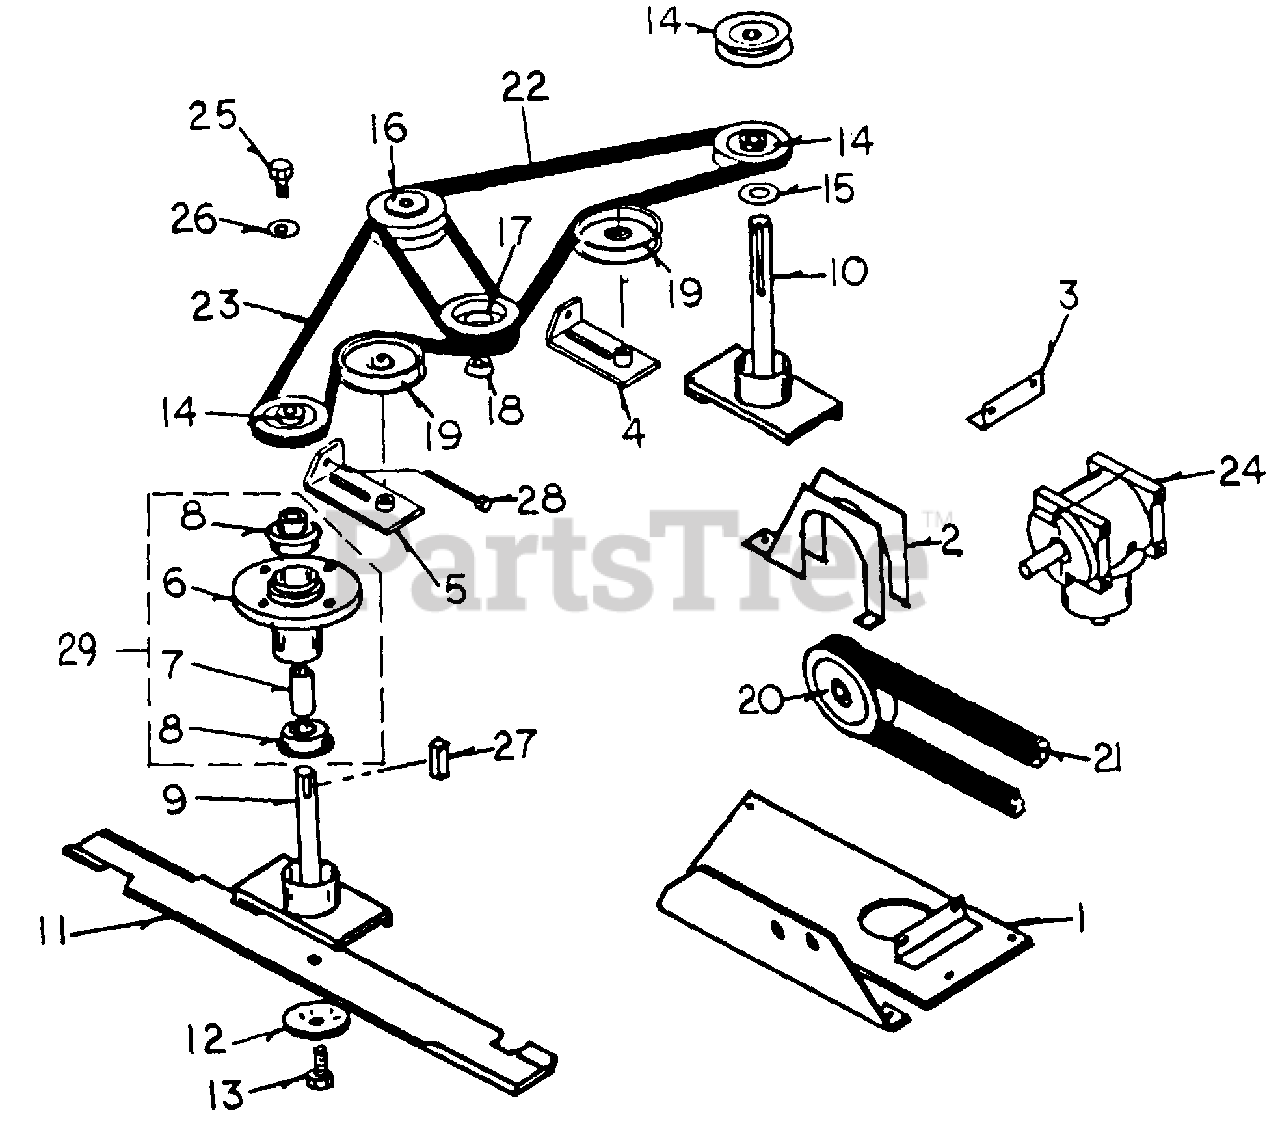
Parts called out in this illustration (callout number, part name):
2	Belt Guard
3	Gearbox Mount Angle
4	Belt Tightener
5	Belt Tightener
6	Spindle Housing
7	Spindle Spacer
8	Spindle Bearing
9	Spindle Shaft
11	Blade
13	Hex Bolt, 3/8-24 x 1 1/4"
14	Spindle Pulley
16	Spindle Pulley, Double A
17	Gearbox Pulley, Output
18	Hub
20	Gearbox Pulley, Input
21	Deck Drive Belt
22	Deck Belt
25	Hex Ny-Lock Bolt, 5/16-24 x 3/4"
26	Washer, 5/16", 10 GA
27	Key Stock, 3/16"
28	Adjustment Bolt
29	Spindle Housing Assembly
